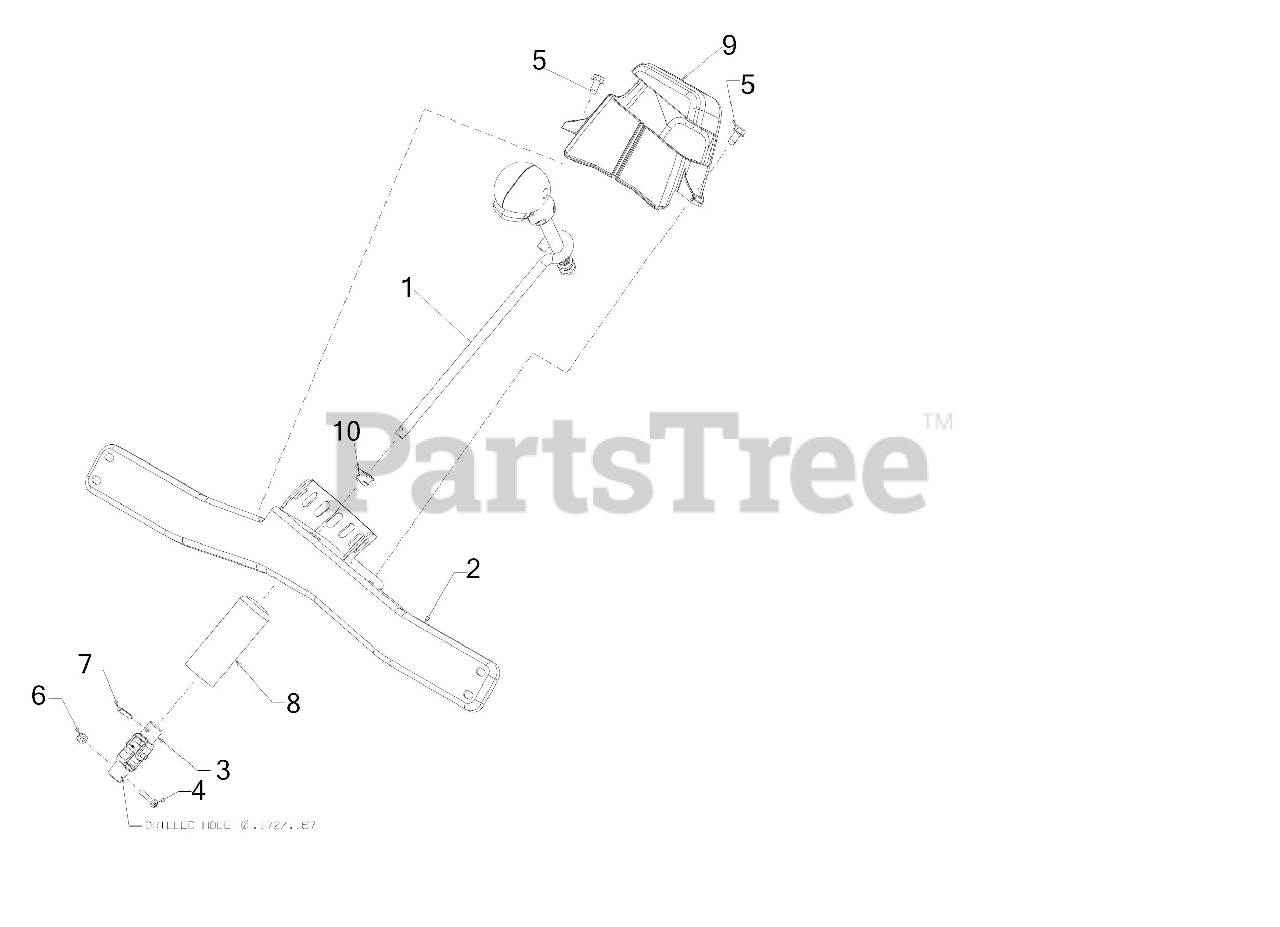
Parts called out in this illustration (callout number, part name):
1	CHUTE CONTROL ASSEMBLY
2	INDICATOR BRACKET
3	JOINT BLOCK ASSEMBLY
4	SCREW #8-32 x .875
5	SCREW 1/4-20 X.500
8	GRIP: 1.18 x 3.33
9	CHUTE ROTATE CONTROL COVER
10	BUSHING .380 ID
